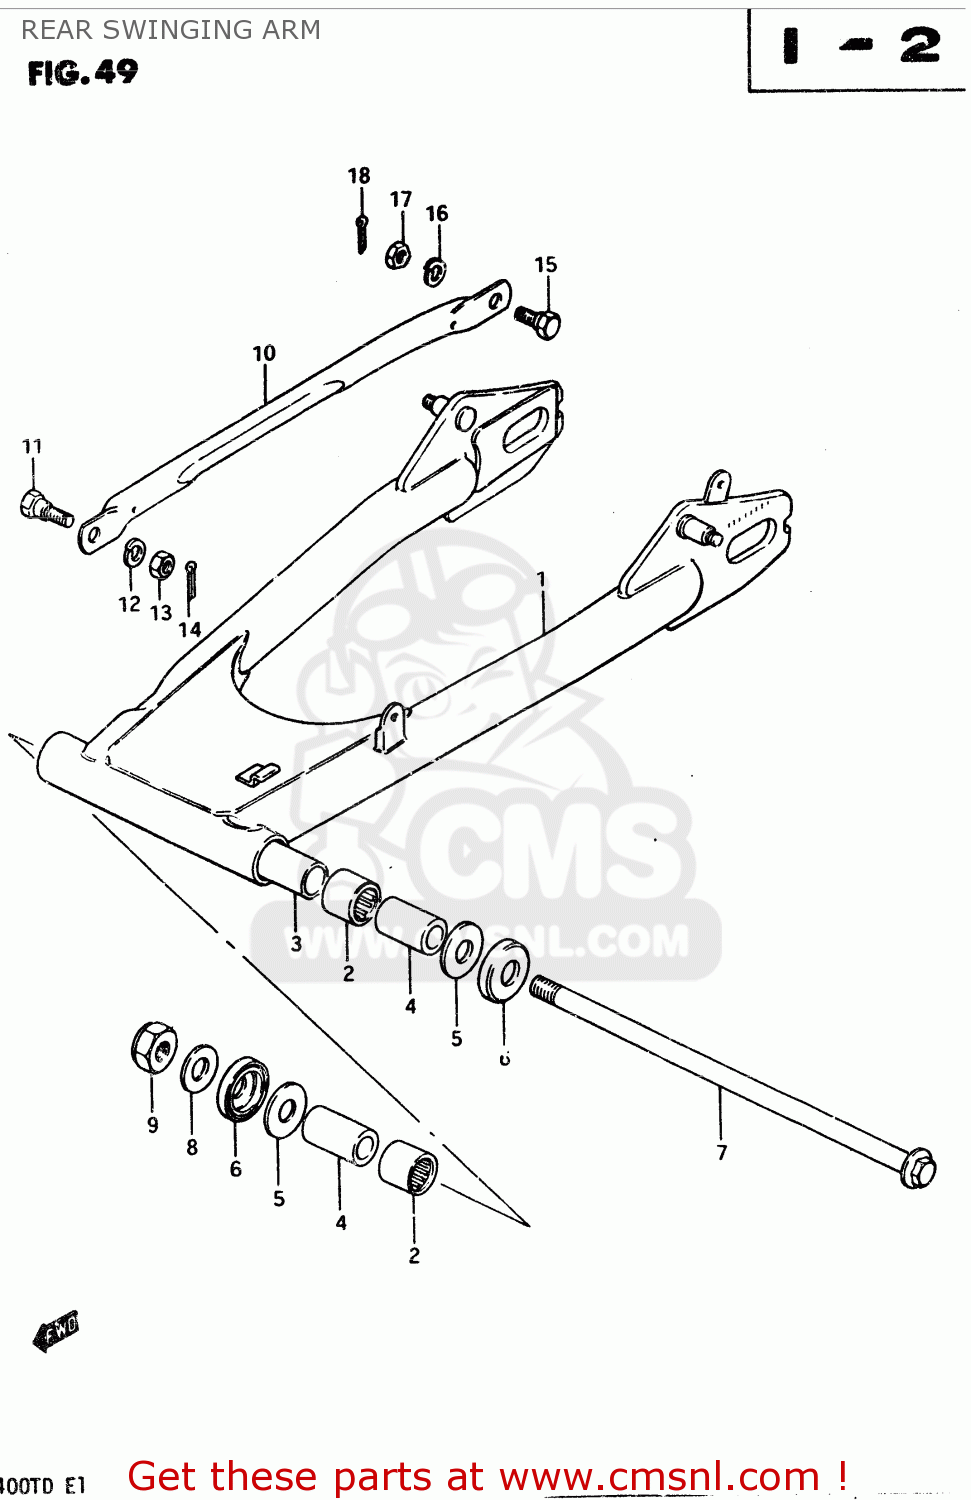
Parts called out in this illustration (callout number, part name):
1	ARM,REAR SWING
2	BEARING(22X29X30)
3	SPACER,SWINGINGARM CTR
4	SPACER,RR SWGARM PIVOT
5	WASHER(14.2X34X1)
6	CVR,RR SWGARM DUST SEAL(OD:40)
7	SHAFT,REAR SWING ARM
8	WASHER
9	NUT 14MM
10	LINK,REAR TORQUE
11	BOLT(10X24.5)
12	LOCK WASHER
13	NUT
14	PIN 20X20
15	BOLT(10X31)
16	LOCK WASHER
17	NUT
18	PIN 20X20
